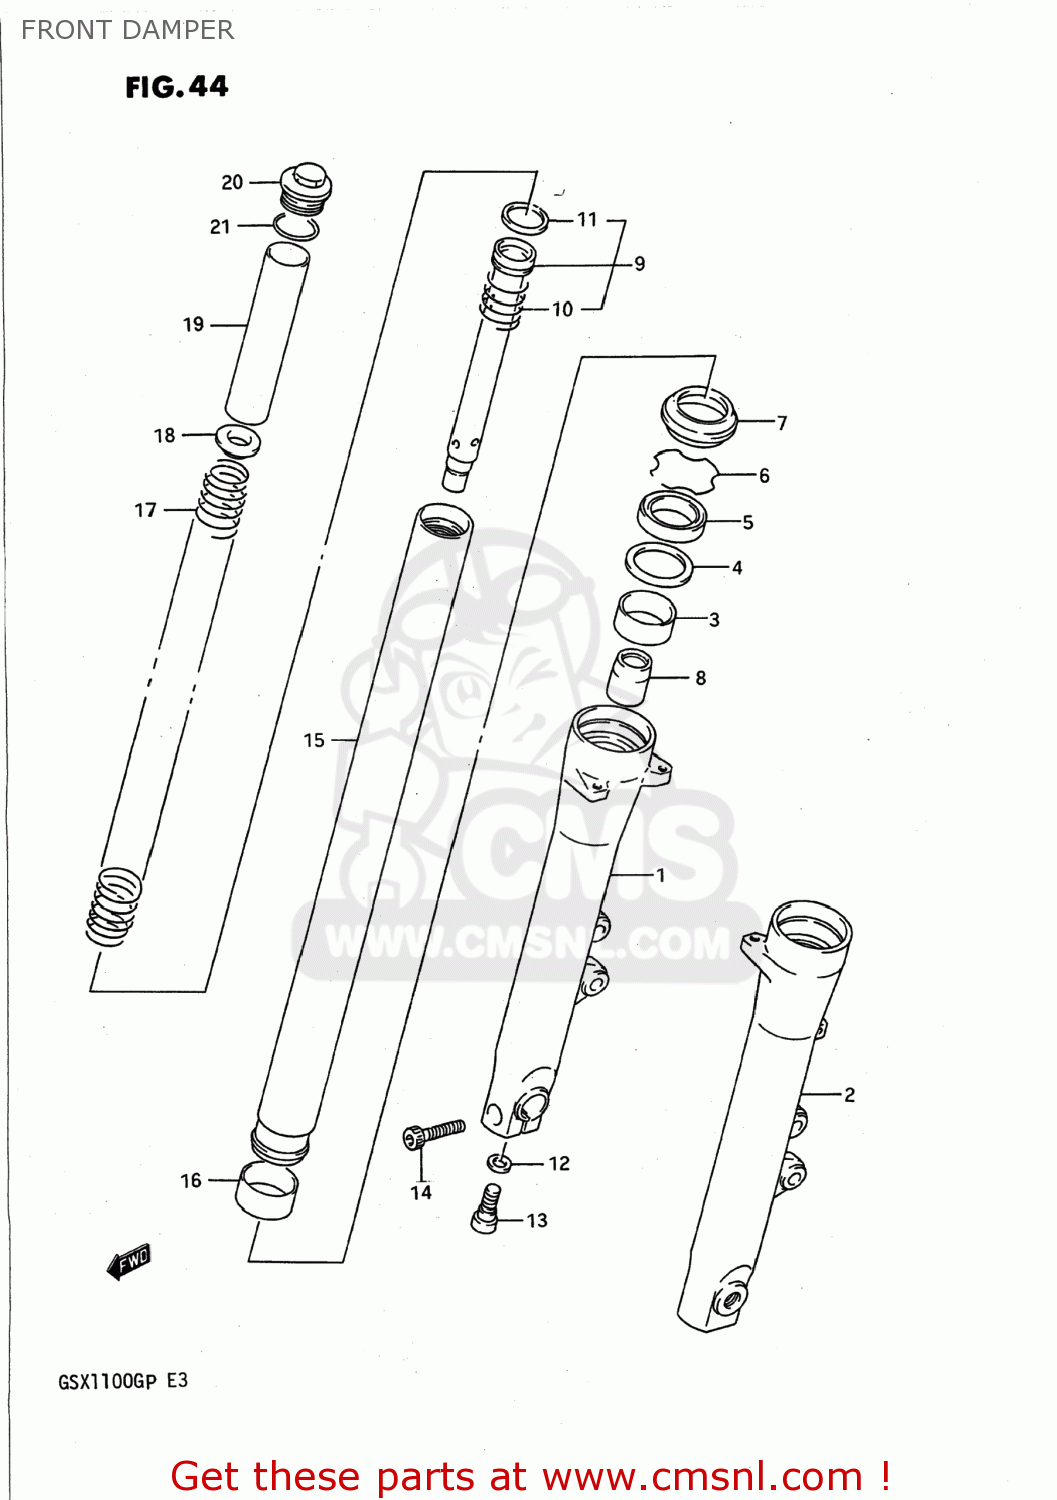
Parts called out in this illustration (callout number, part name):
1	TUBE,OUTER,RIGHT
2	TUBE,OUTER,L
3	METAL,SLIDE
4	WASHER
5	OIL SEAL,FRONT FORK
6	RING,STOPPER
7	SEAL,DUST
8	PIECE,OIL LOCK
9	CYLINDER
10	SPRING,REBOUND
11	RING,PISTON
12	GASKET (NAS)
13	BOLT(14X25)
14	BOLT
15	TUBE,INNER
16	PISTON
17	SPRING,MAIN
18	GUIDE,SPRING
19	SPACER
20	CAP,FORK
21	O RING
